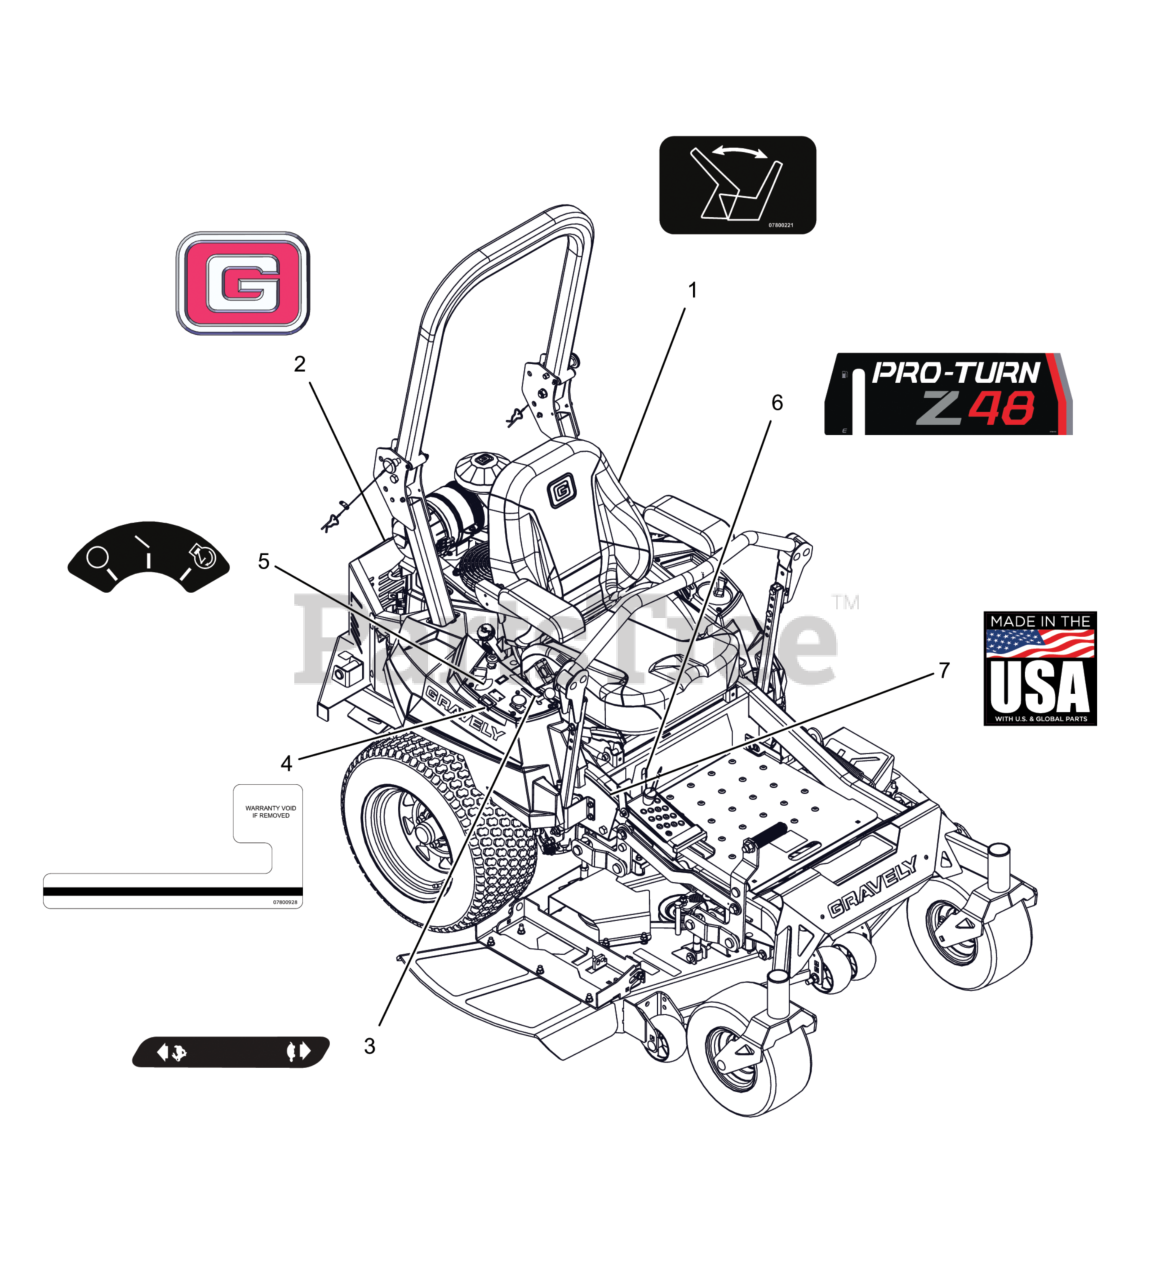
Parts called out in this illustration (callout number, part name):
1	DECAL, SEAT RELEASE
2	DECAL, GRAVELY BRAND
3	DECAL, DASH
4	DECAL, HOURMETER - SECURITY
5	DECAL, KEYSWITCH
6	DECAL, PRO - TURN Z48
7	DECAL, MADE IN USA
